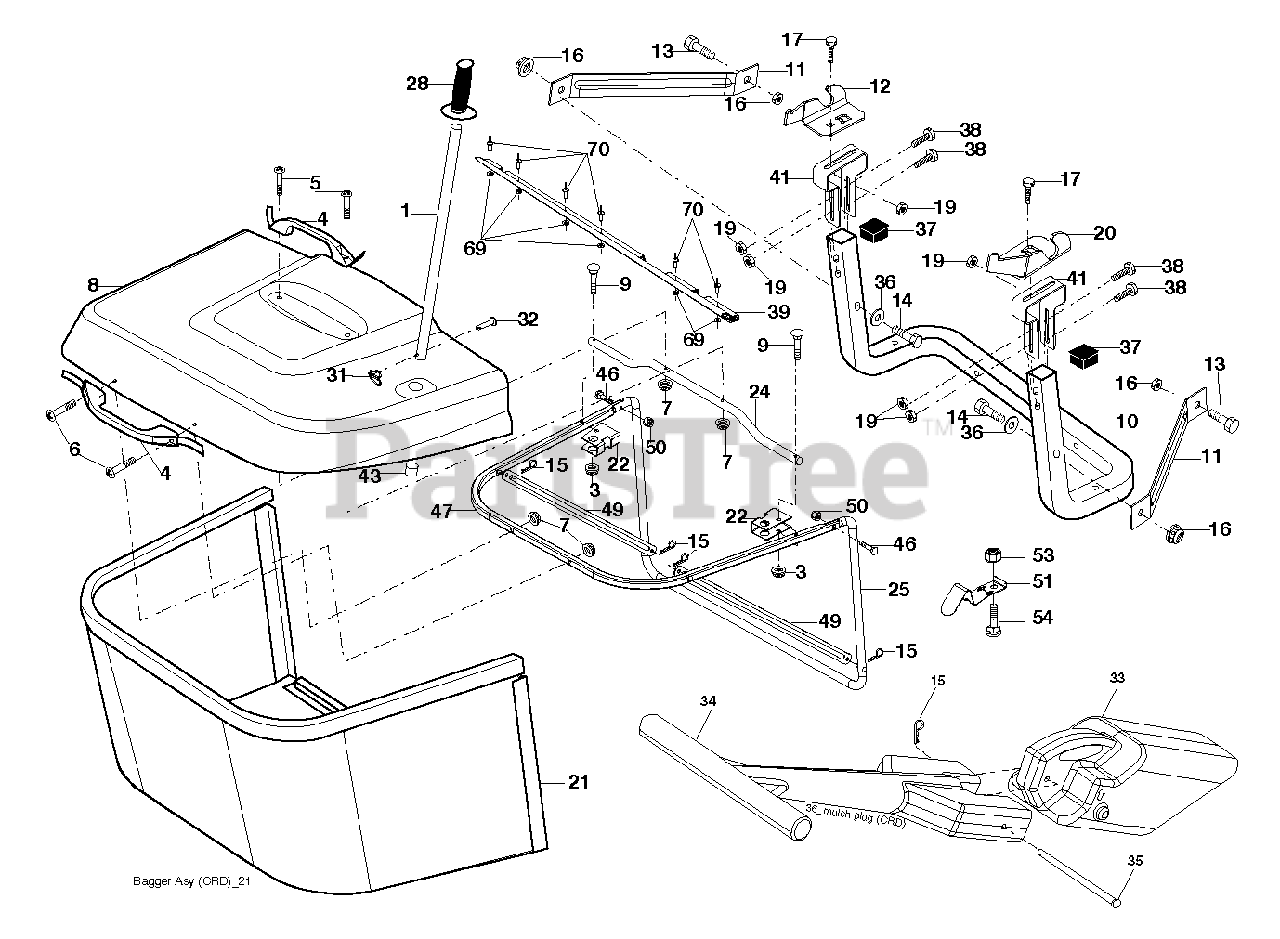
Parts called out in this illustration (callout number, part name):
1	TUBE.PNT.HDL.BAGGER.
3	NUT T
5	SCREW.PAN.HEAD
11	BRACKET
14	BOLT-HEX EAK
15	RETAINER-SPRNG RB
16	NUT LOCK FLG 3/8-16 UNC
17	BOLT
19	NUT LOCK HEX FLANGE 5/16-18
20	BRKT.PIVOT.RH.CRD
21	BAGGER.ASM.CRD.2007
22	BRACKET.BAGGER.SD.
24	TUBE
28	GRIP.HANDLE.BLACK
31	RETAINER CLIP
32	RIVET,DRILLED
33	MULCHING.PLUG.1078.CRD.NON-TEX
35	PIN
38	BOLT.5/16-18X2.5
39	SEAL.BAGGER.CRD
41	BRACKET.BAGGER.SD.
43	PLUG, TUBING END
46	BOLT.CARRIAGE.5/16-18
50	NUT.71038.31-18.HEX.NYLOCK
53	NUT
54	BOLT
